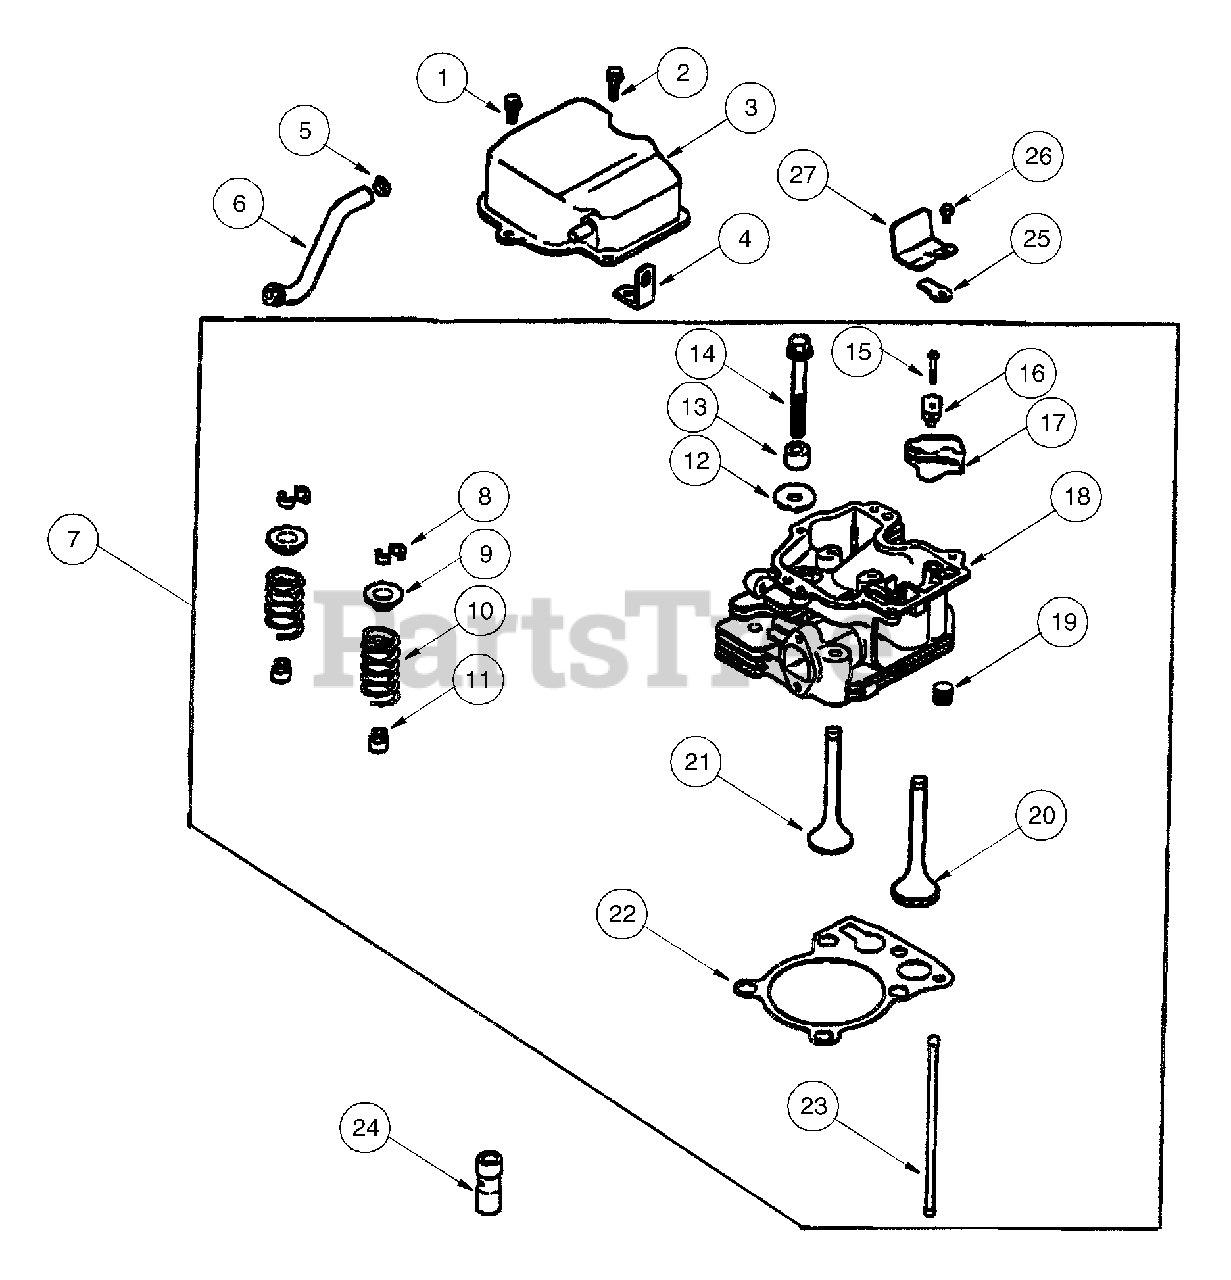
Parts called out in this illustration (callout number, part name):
1	Screw, Hex Flange, M6 x 1 x 20
2	Screw, Hex Flange, M6 x 1 x 25
3	Cover, Valve w/Nipple
4	Strap, Lifting
5	Clamp, Hose
6	Hose, Breather
7	Kit, Cyl Head,
8	Kit, Retainer
9	Cap, Valve Spring
10	Spring, Valve
11	Seal, Valve Stem
12	Washer, Plain, 13/32"
13	Spacer, Head Bolt Exhaust Port
14	Screw, Hex Flange, M10 x 1.5 x 81
15	Screw, Hex Flange, M6 x 1 x 34
16	Pivot, Rocker Arm
18	Head, Cylinder
19	Plug, Allen Head, 1/8" Pipe
20	Valve, Intake (Std.)
21	Valve, Exhaust (Std.)
22	Gasket, Cylinder Head
23	Rod, Push
24	Lifter, Valve
25	Reed, Breather
26	Screw, Hex Flange, M5 x .8 x 10
27	Retainer, Breather Reed
